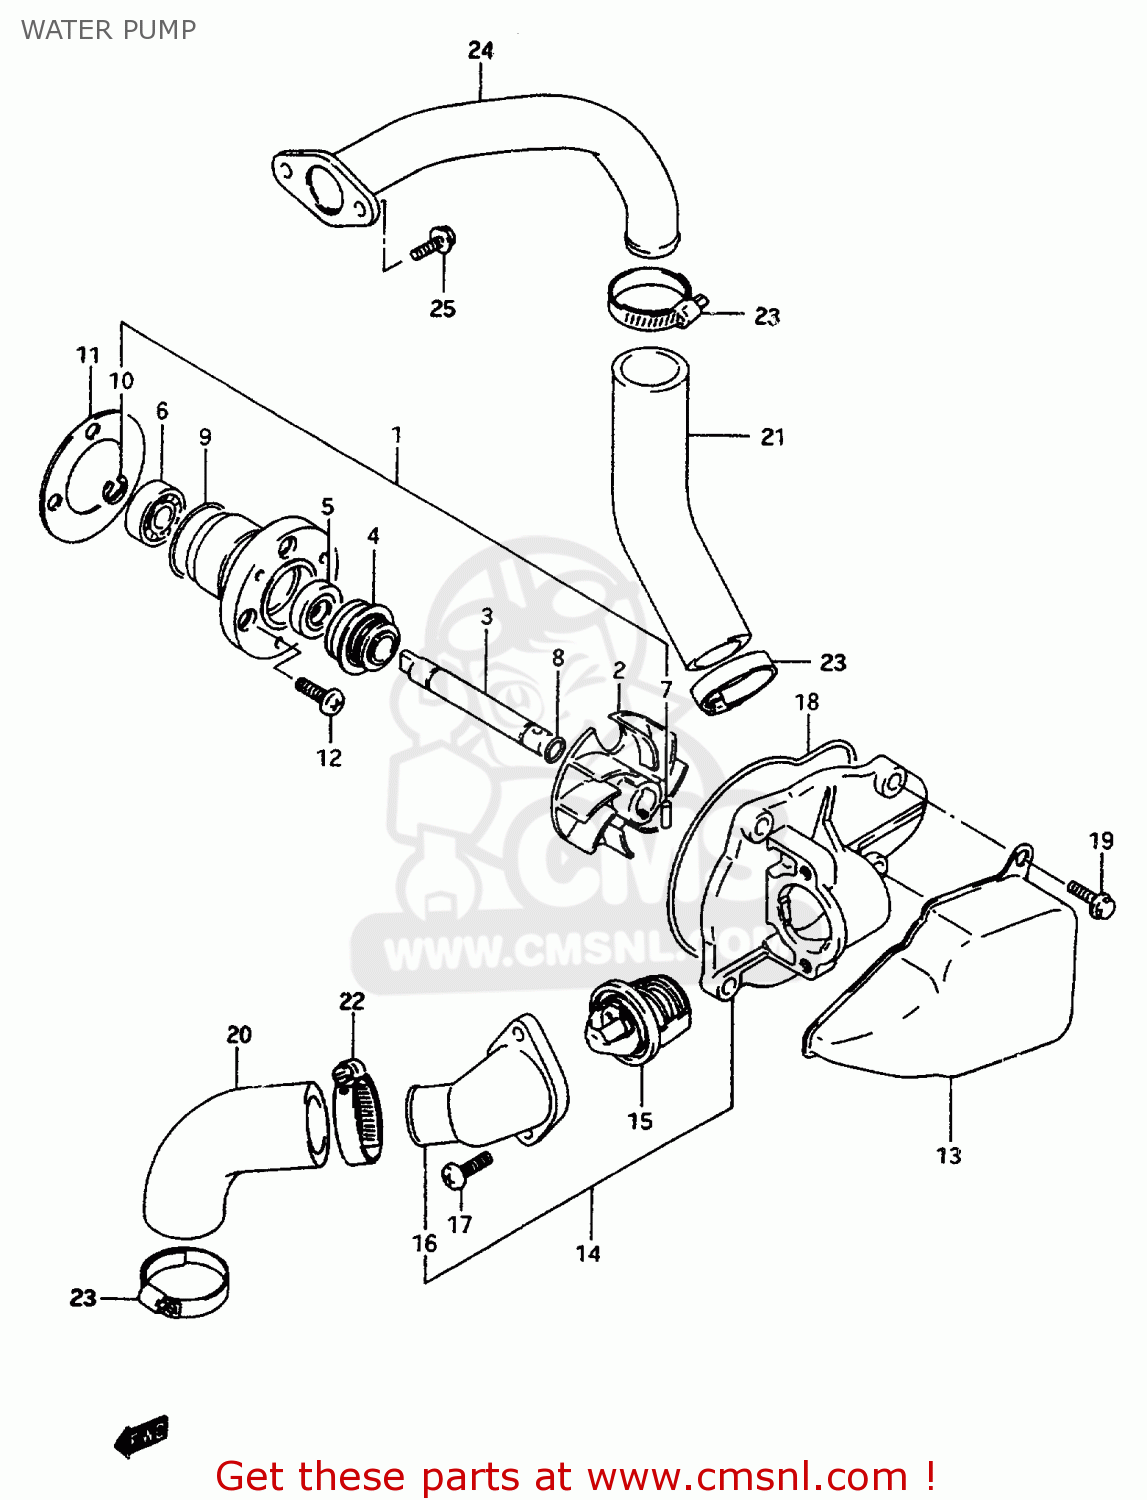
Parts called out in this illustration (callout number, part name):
1	PUMP ASSEMBLY,WATER
2	IMPELLER
3	SHAFT
4	SEAL,MECHANICAL
5	SEAL,OIL(10X21X5)
6	BEARING,10X26X8
7	PIN
8	O RING
9	O RING
10	E RING
11	GASKET,WATER PUMP (NAS)
12	SCREW
13	COVER,WATER PUMP
14	CASE ASSY,WATER PUMP
15	THERMOSTAT,WATER
16	CONNECTOR
17	SCREW
18	O RING,WATER PUMP CAP
19	BOLT
20	HOSE,WATER PUMP IN
21	HOSE,WATER PUMP OUTLET
22	CLAMP
23	CLAMP
24	PIPE,CYLINDER INLET
25	BOLT
